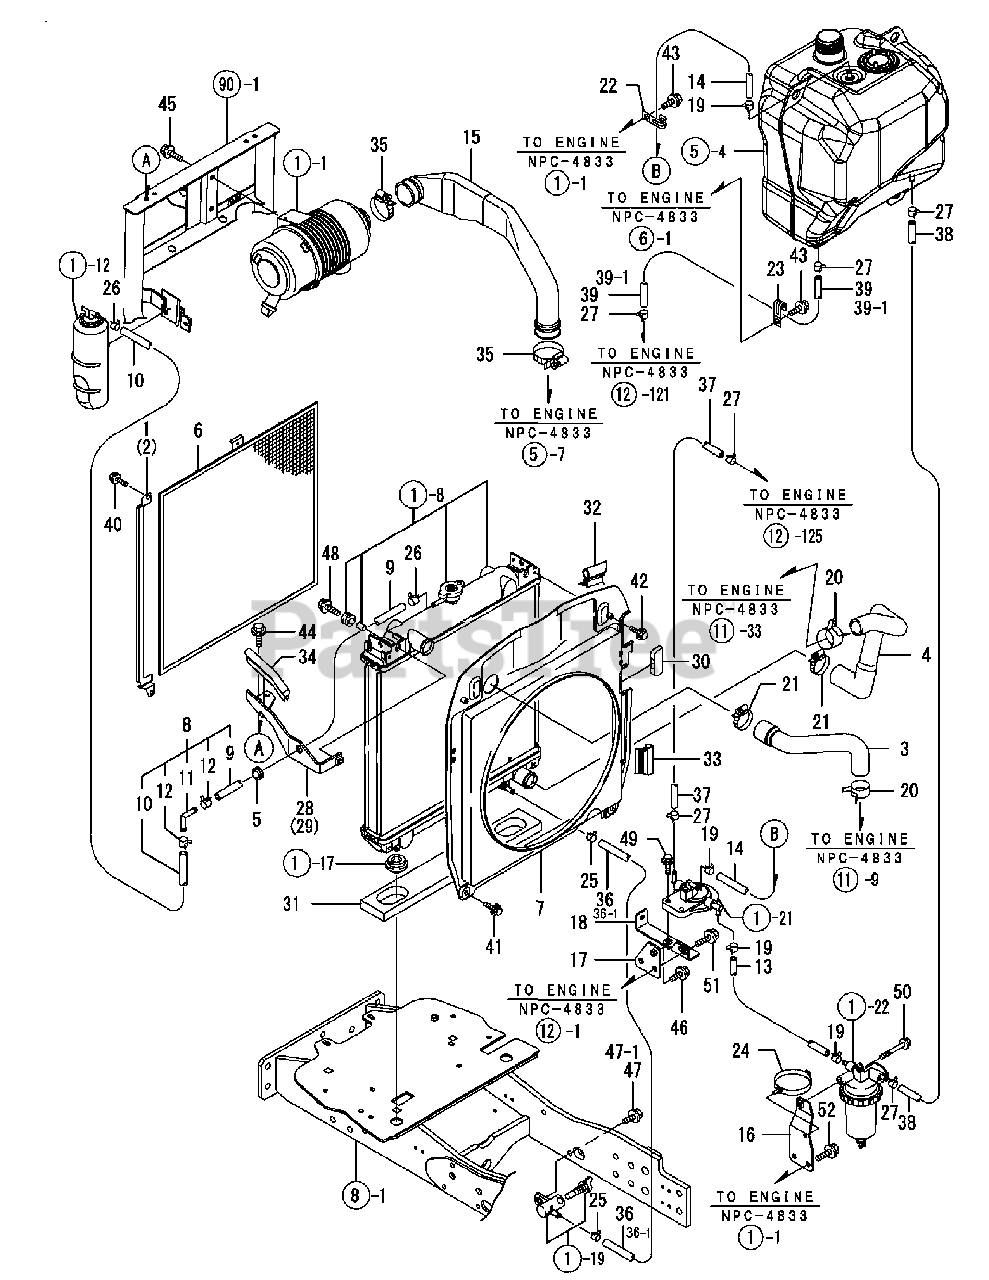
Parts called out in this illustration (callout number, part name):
1	RAIL, RADIATOR L
2	RAIL, RADIATOR R
5	GROMMET 13
6	SCREEN, RADIATOR
8	HOSE ASSY, OVERFLOW
9	HOSE, OVERFLOW A
10	HOSE, OVERFLOW B
16	BRACKET, SEPARETOR
17	BRACKET A, FILTER
18	BRACKET B, FILTER
20	BAND, HOSE 38
22	CLAMP, WIRE HARNESS
23	CLAMP, WIRE HARNESS
28	STAY ASSY, L.H.
29	STAY ASSY, R.H.
30	GROMMET SHROUD
31	URETHANE, RADIATOR
32	WEATHER-STRIP, A
33	WEATHER-STRIP, B
34	WEATHER-STRIP, 195
36	HOSE, 7.3 X 270
36-1	HOSE, 7.3 X 250
37	HOSE, 7.3 X 270
38	HOSE 7.3,BRAIDED
39	HOSE, 7.3 X 850
39-1	HOSE, 7.3 X 890
40	BOLT M 6X 12 PLATED
41	BOLT M 6X 12 PLATED
42	BOLT M 6X 25 PLATED
43	BOLT M 8X 12 PLATED
44	BOLT M 8X 16 PLATED
45	BOLT M 8X 16 PLATED
46	BOLT M 8X 16 PLATED
47	BOLT M 8X 25 PLATED
47-1	BOLT M 8X 30 PLATED
48	BOLT M 8X 25 PLATED
49	BOLT M 8X 25 PLATED
50	BOLT M 8X 70 PLATED
51	BOLT M10X 20 PLATED
52	BOLT M10X 20 PLATED
